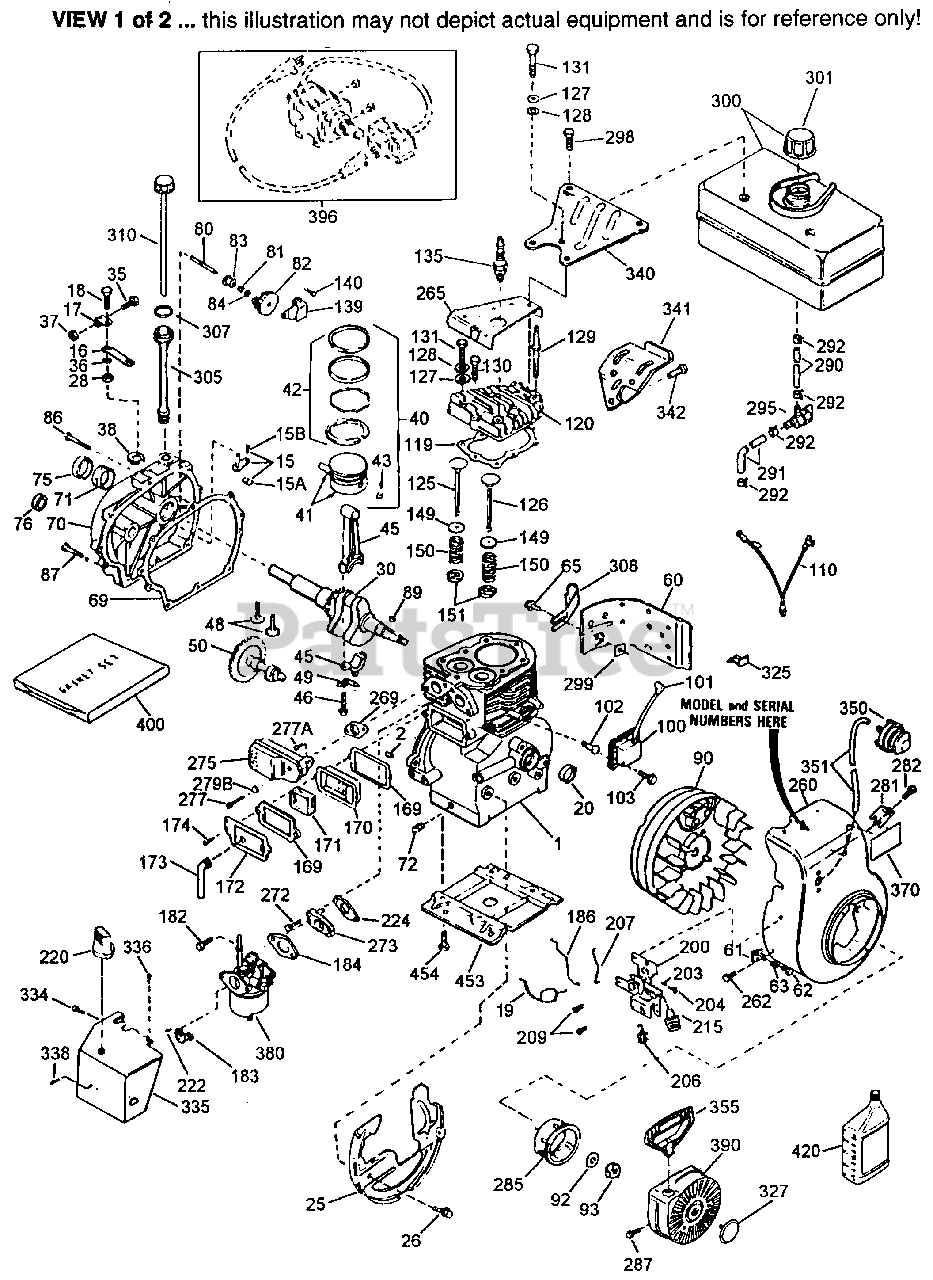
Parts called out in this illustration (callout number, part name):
1	"Cylinder (Incl. 2 & 20)
2	Dowel Pin
15	Governor Rod (Incl. 15A & 15B)
15A	Governor Yoke
15B	Screw, 6-40 x 5/16"
16	Governor Lever
17	Governor Lever Clamp
18	Screw, 8-32 x 5/16"
19	Speed Control Spring
20	Oil Seal
25	Blower Housing Baffle
26	Screw, 1/4-20 x 5/8"
28	Lock Nut, 8-32
30	Crankshaft
35	Screw, 10-32 x 3/4"
36	Lock Washer #8
37	Lock Nut, 10-32
38	Retaining Ring
40	Piston, Pin & Ring Set (Std.)
40	Piston, Pin & Ring Set (.010" OS)
40	Piston, Pin & Ring Set (.020" OS)
41	Piston & Pin Ass'y. (Std.) (Incl. 43)
41	Piston & Pin Ass'y. (.010" OS) Incl. 43
41	Piston & Pin Ass'y. (.020" OS) Incl. 43
42	Ring Set (Std.)
42	Ring Set (.010" OS)
42	Ring Set (.020" OS)
43	Piston Pin Retaining Ring
45	Connecting Rod Ass'y. (Incl. 46 & 49)
46	Connecting Rod Bolt
48	Valve Lifter
49	Oil Dipper
50	Camshaft (MCR)
60	Blower Housing Extension
61	Grommet Mounting Bracket
62	Screw, 8-32 x 3/8"
63	Breather Tube Grommet
65	Screw, 10-24 x 1/2"
69	* Cylinder Cover Gasket
70	Cylinder Cover (Incl. 71, 75 & 80)
71	Crankshaft Bushing
72	Oil Drain Plug (Sq. hd., 1/4-18)
75	Oil Seal
80	Governor Shaft
82	Governor Gear Ass'y.
83	Governor Spool
84	Retaining Ring
86	Screw, 1/4-20 x 1-1/4"
87	Screw, 1/4-20 x 1-3/4"
89	Flywheel Key
90	Flywheel
92	Belleville Washer
93	Flywheel Nut
100	Solid State Ignition
101	Spark Plug Cover
102	Solid State Mounting Stud
103	Screw, Torx T-15, 10-24 x 1"
110	Ground Wire (One male, One female, On e eyelet)
119	* Cylinder Head Gasket
120	Cylinder Head (Incl. 3 of 131)
125	Exhaust Valve (Std.)(Incl. 151)
125	Exhaust Valve (1/32" OS) (Incl. 151)
126	Intake Valve (Std.) (Incl. 151)
126	Intake Valve (1/32" OS) (Incl. 151)
128	Belleville Washer
129	Screw, 5/16-18 x 2-1/2"
130	Screw, 5/16-18 x 2-1/2"
131	Screw, 5/16-18 x 2-1/2"
135	Resistor Spark Plug - RJ17LM
139	Governor Gear Bracket
140	Screw, Torx T-25, 10-24 x 1/2"
149	Valve Spring Cap
150	Valve Spring
151	Valve Spring Keeper
169	* Valve Cover Gasket
170	Breather Body
171	Breather Element
172	Valve Cover
173	Breather Tube
174	Screw, 10-24 x 1/2"
182	Screw, 1/4-20 x 27/32"
183	Choke Bracket
184	* Carburetor To Intake Pipe Gasket
186	Governor Link
200	Control Bracket (Incl. 203,204 & 206)
203	Compression Spring
204	Screw, 5-40 x 7/16"
206	Terminal
207	Throttle Link
209	Screw, 10-32 x 1/2"
215	Control Knob
220	Control Knob
222	Screw, 10-32 x 1/2"
224	* Intake Pipe Gasket
260	Blower Housing
262	Screw, T-40, 5/16-24 x 21/32"
264A	Screw, 5/16-18 x 3/4"
265	Cylinder Head Cover
269	* Exhaust Manifold Gasket
272	Screw, 5/16-18 x 3/4"
273	Carburetor Flange
275	Muffler
277	Screw, 5/16-18 x 2"
281	Starter Bubble Cover
282	Screw, 8-32 x 3/8"
285	Starter Cup
287	Screw, 8-32 x 21/64"
290	Fuel Line (8.62")
291	Fuel Line
292	Fuel Line Clamp
295	Fuel Shut-Off Valve (Incl. 292) also available in Packaged Part #740073
298	Screw, 1/4-15 x 3/4"
299	"U" Type Nut
300	Fuel Tank (Incl. 292 & 301)
301	Fuel Cap (Red)
305	Oil Fill Tube
307	"O" Ring
308	Fill Tube Clip
310	Dipstick
325	Wire Clip
327	Starter Plug
334	Screw, 8-32 x 5/16"
335	Carburetor Cover
336	Screw, 10-32 x 1/2"
338	Screw, 8-32 x 3/8"
340	Fuel Tank Bracket
341	Fuel Tank Bracket
342	Screw, 1/4-20 x 5/8"
350	Primer Ass'y.
351	Primer Line
355	Starter Handle (Mitten Grip) also ava ilable in Packaged Part #740053B
370	Instruction Decal
370A	Name Decal
370B	Warning Decal
370C	Primer Decal
370D	Choke Decal
370E	Control Decal
380	Carburetor (Incl. 184)
390	Rewind Starter
400	* Gasket Set (Incl. items marked PK in notes) Incl. part #'s 26756 (1),27272 A (3), 27896A (2), 27915A (1),29673 ( 1), 30684 (1), 31688A (1),32631A (1), 33355A (1), 35865 (3)
420	SAE 5W30 4-Cycle Engine Oil - Quart - Winter
453	Engine Mounting Base
454	Screw, 5/16-18 x 3/4"
